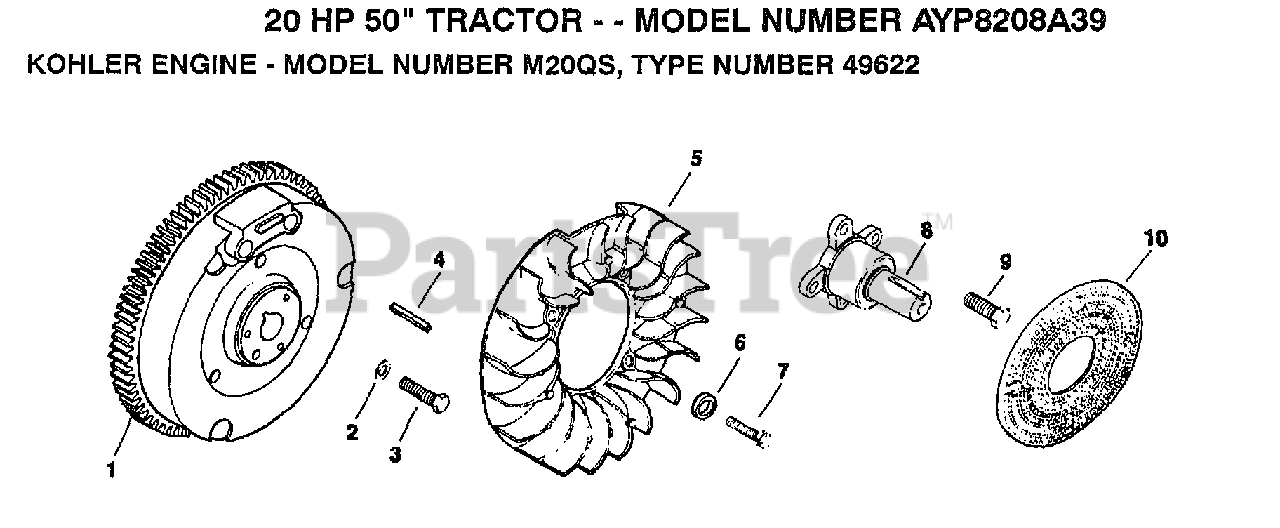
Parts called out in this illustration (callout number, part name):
2	WASHER, PLAIN
8	SHAFT, FRONT DRIVE
10	SCREEN, GRASS
